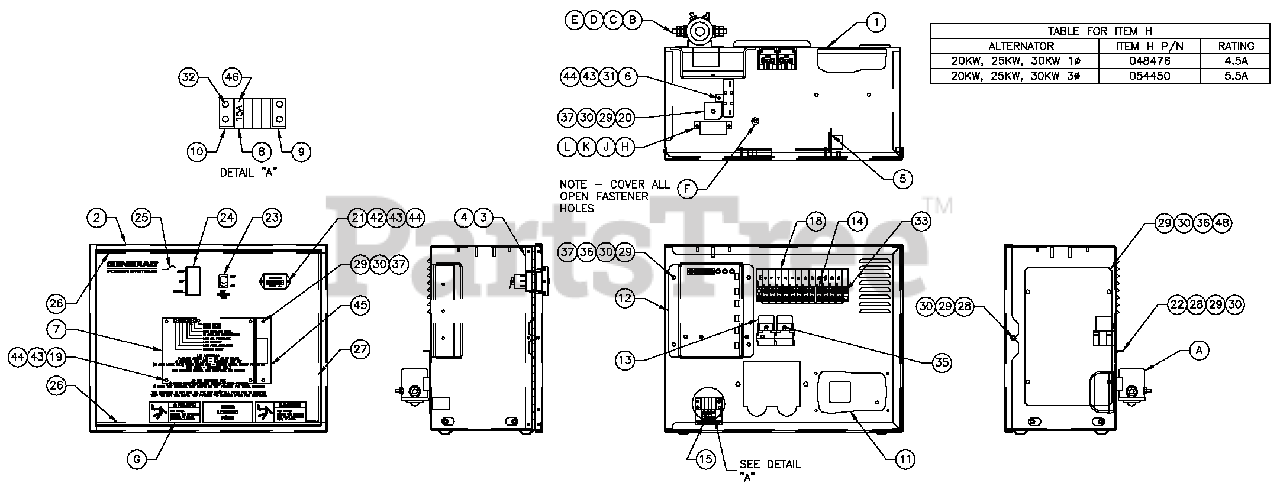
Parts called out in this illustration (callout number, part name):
1	ENCL HSB CONTROL PANEL
2	COVER CONTROL PNL W/HOUR METER
3	HINGE CONTINUOUS H-PANEL
4	RIVET POP .125 X .275 SS
5	SCREWPPPH HI - LO#4 -24X 3/8
6	WASHERFLATM3
7	ASSY PCB R-200A CNTRL 3600
8	HOLDER FUSE WICKMANN 178.6150
9	ADPTR RHSIDEWICKMAN 178.6191
10	ADPTRLH SIDE WICKMAN 17816192
11	BATC 13.4VDC 2.5AW/8POS PLUG
12	ASSY VOLTAGE REGULATOR 60HZ
13	RELAY 12VDC C FORM W/DIODE
14	BLOCK TERM 20A12 X 6X1100V
15	DECAL CPL CONTROL PANEL FUSES
18	DECAL CPL3.9LTB1
19	SPACER 9.5H 3.2 ID
20	DIO BRIDGE 25A600V
21	HOUR METER 10-80VDC
22	PLATE HARNESS CLAMP
23	SWITCH RKR DPST125VSPD
24	SWITCH RKR DPDT ON-OFF-ON
25	DECAL CONTROL PNL W/HOUR METER
26	SEAL COVER 318 X12.7 X382
27	SEAL COVER 318 X12.7 X283
28	SCREWHHPM M5 -0.8X 12
29	WASHERFLATM5
30	WASHERLOCKM5
31	RES WW15R 5 ) 25W QK CONN
32	S CREW PHTT M3.5-0.6 X 10
33	S CREW PHTT M3.5-0.6 X 16
35	S CREW PHTT M4-0.7 X 10 ZYC
36	S CREW PPHM M5-0.8 X 12 ZNC
37	NUT HEX M5-0.8G8 CLEAR ZINC
42	SCREWPHM M3-05X 10BLACK
43	WASHERLOCKM3
44	NUT HEX M3-0.5G8 YEL CHR
45	SUPPORT ANGLEPCB
46	FUSEATO TYPE 15AMP(BLUE)
47	HARN CTRL PNL R-200LOWKW (NOTSHOWN)
48	PLATE COVER H PANEL
A	RELAY SOLENOID 12VDC PNLMNT
B	SCREW HHC 1/4-20X3/4 G5
C	WASHERFLAT1/4-M6ZINC
D	WASHERLOCK M6-1/4
E	NUT HEX 1/4-20STEEL
F	SEAL WEATHER .43'DIA
G	DANGER HIGH VOLTAGE (SPANISH)
H	CIRCUIT BREAKER
J	WASHERFLAT M3
K	WASHERLOCK M3
L	NUT HEX M3-0.5G8 YEL CHR
